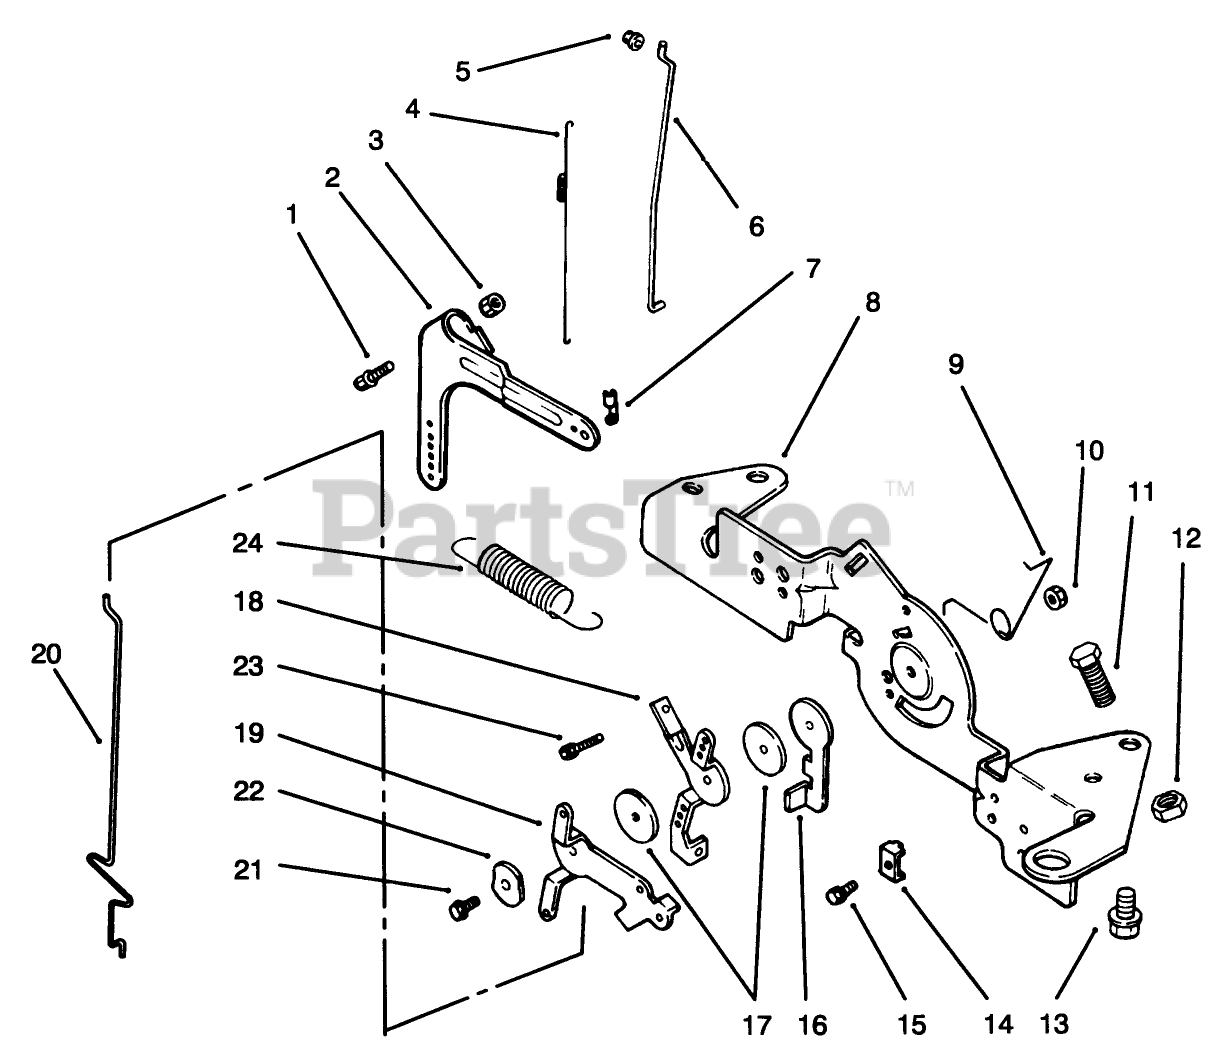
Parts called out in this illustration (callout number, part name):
2	Lever-Governor
4	Spring-Linkage
5	Bushing
6	Linkage-Throttle (Only On: 72103)
7	Bushing-Linkage
8	Bracket-Control
9	Spring-Choke Return
16	Lever-Throttle Actuator
18	Lever-Throttle Control
19	Lever-Choke
20	Linkage-Choke (Only On: 72103, 72083)
22	Washer-Wave
23	Screw-Hex.
24	Carriage Bolt
